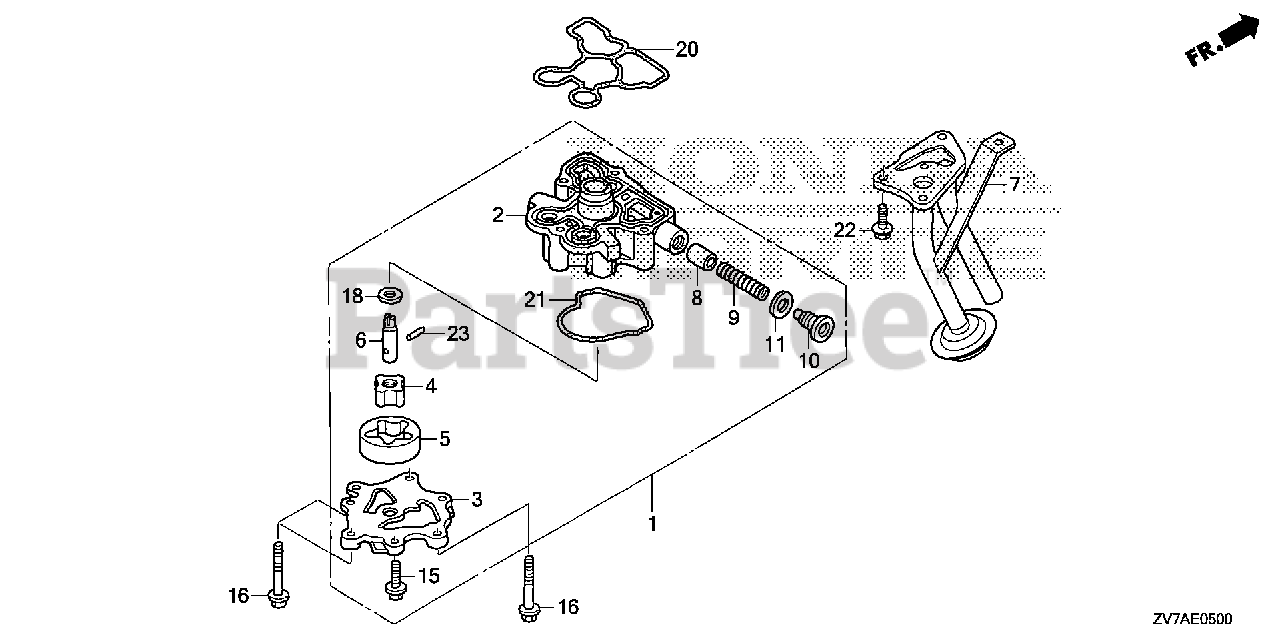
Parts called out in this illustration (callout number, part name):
1	PUMP ASSY., OIL
2	BODY, OIL PUMP
3	COVER, OIL PUMP
4	ROTOR, OIL PUMP (INNER)
5	ROTOR, OIL PUMP (OUTER)
6	SHAFT, OIL PUMP
7	STRAINER, OIL
8	VALVE, RELIEF
9	SPRING, RELIEF VALVE
10	BOLT, SEALING (14MM)
11	WASHER, SEALING (14MM)
15	BOLT, FLANGE (6X18) (CT200)
16	BOLT, FLANGE (6X45)
18	WASHER, THRUST (11MM)
20	O-RING, PUMP COVER
21	O-RING, PUMP COVER
22	BOLT, FLANGE (6X16)
23	ROLLER (4X15.8)
